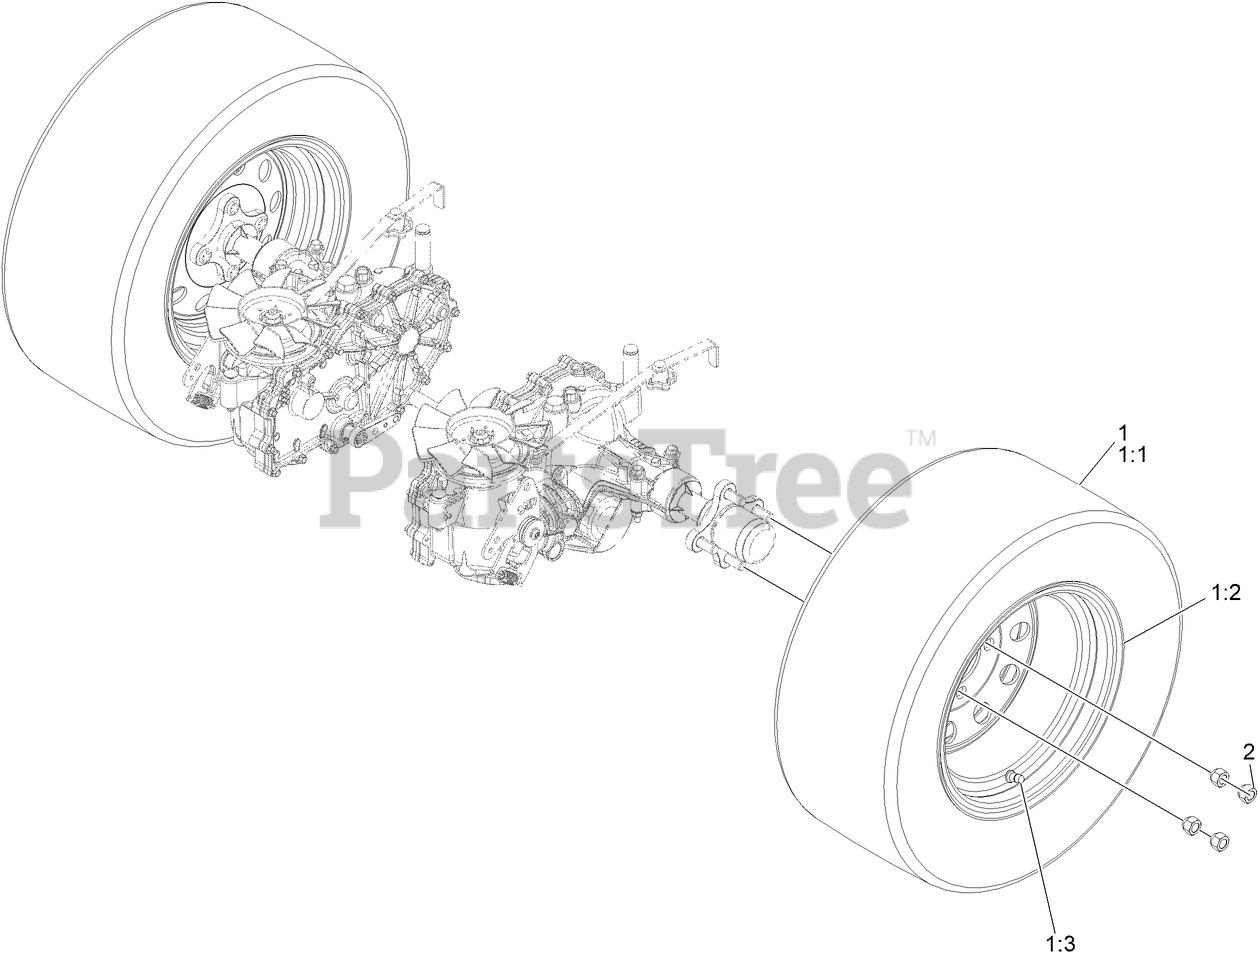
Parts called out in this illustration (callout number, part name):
1	Wheel And Tire ASM
1:3	VALVE
2	NUT-LUG
